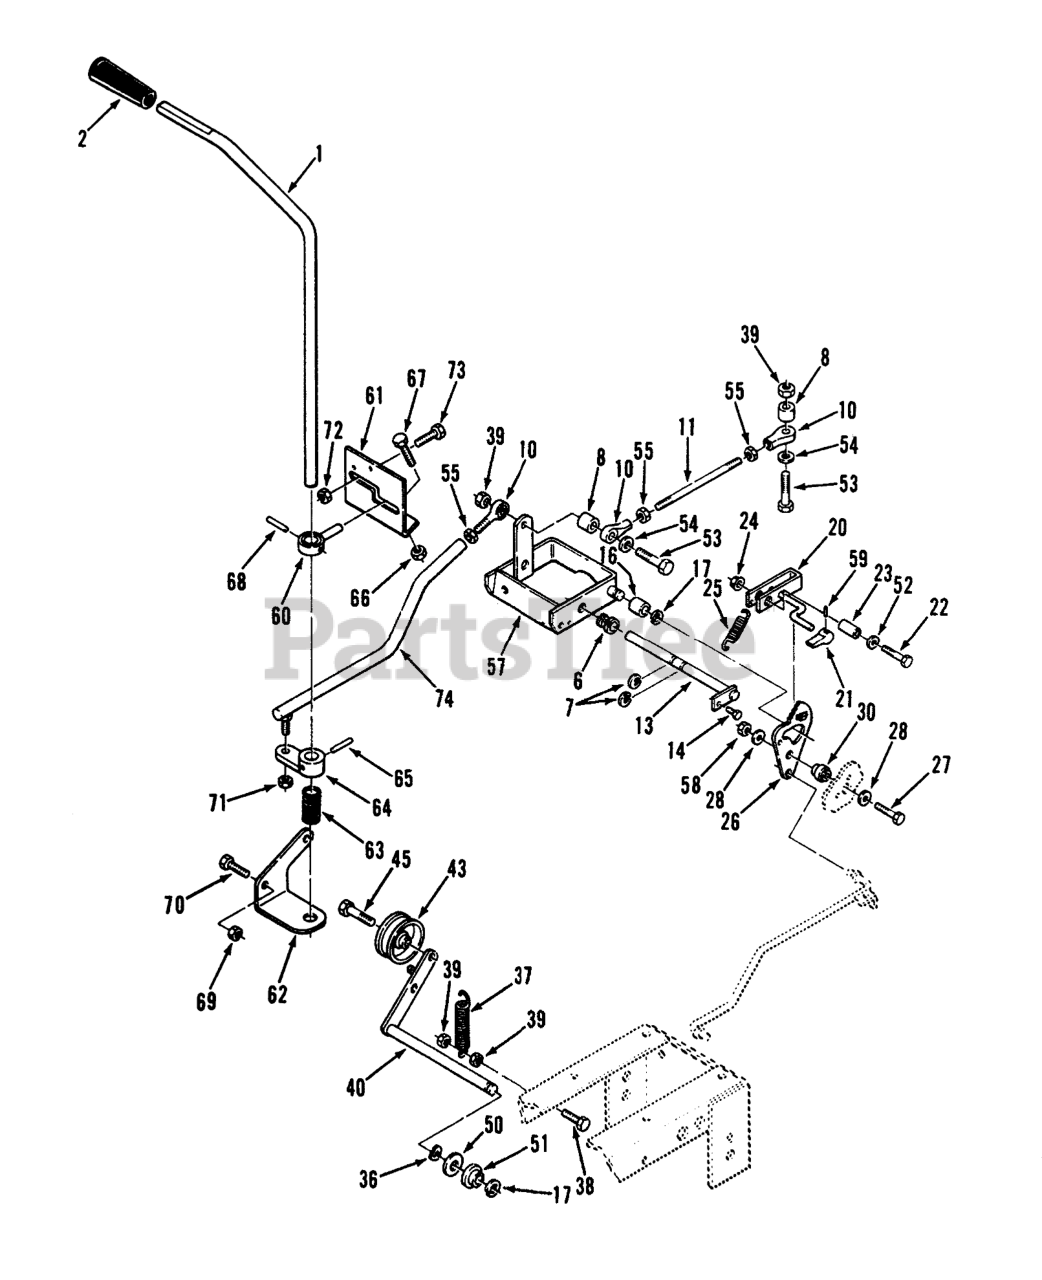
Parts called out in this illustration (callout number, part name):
1	ROD-MOTION CONTROL
2	Knob-Motion Control
6	NYLINER BUSHING
7	RING-RETAINING, EXTERNAL
8	Spacer
10	ROD END, 1/4-28
11	ROD-CONTROL
13	ASSY-ROD CAM PIVOT
14	SCREW
16	BEARING-CAM RETURN
17	RING-RETAINING, EXTERNAL
20	Lever-Parking Brake
21	KNOB-PARKING BRAKE
22	SCREW-HH
23	SPACER
24	LOCKNUT-FLANGE
25	Spring
26	Cam Plate
27	SCREW-HH
28	WASHER-FLAT
30	Spacer
36	WASHER-WAVE
37	SPRING-EXTENSION
38	SCREW-HH
39	NUT-LOCK
40	WLDMT-IDLER ARM
42	Pin-Cotter
43	PULLEY-IDLER
45	BOLT-SPECIAL HEX
50	WASHER-FLAT
51	BUSHING-FLANGED
52	WASHER-FLAT
53	SCREW-HH
54	WASHER-FLAT
55	NUT-JAM
57	Cam Comtrol
58	NUT-LOCK, NI
59	PIN-SPIROL 3/32X5/8
60	GUIDE-CONTROL
61	Bracket-Control
62	Bracket-Control
63	SPRING-COMPRESSION
64	ARM-CONTROL
65	Pin-Spirol
66	NUT-LOCK, NI
67	SCREW-HH
68	SPIROL PIN 7/32X7/8
69	NUT-LOCK, NI
70	SCREW-HH
71	NUT-LOCK
72	NUT-LOCK, NI
73	SCREW-HH
74	ASSY-ROD & BALL JOINT
